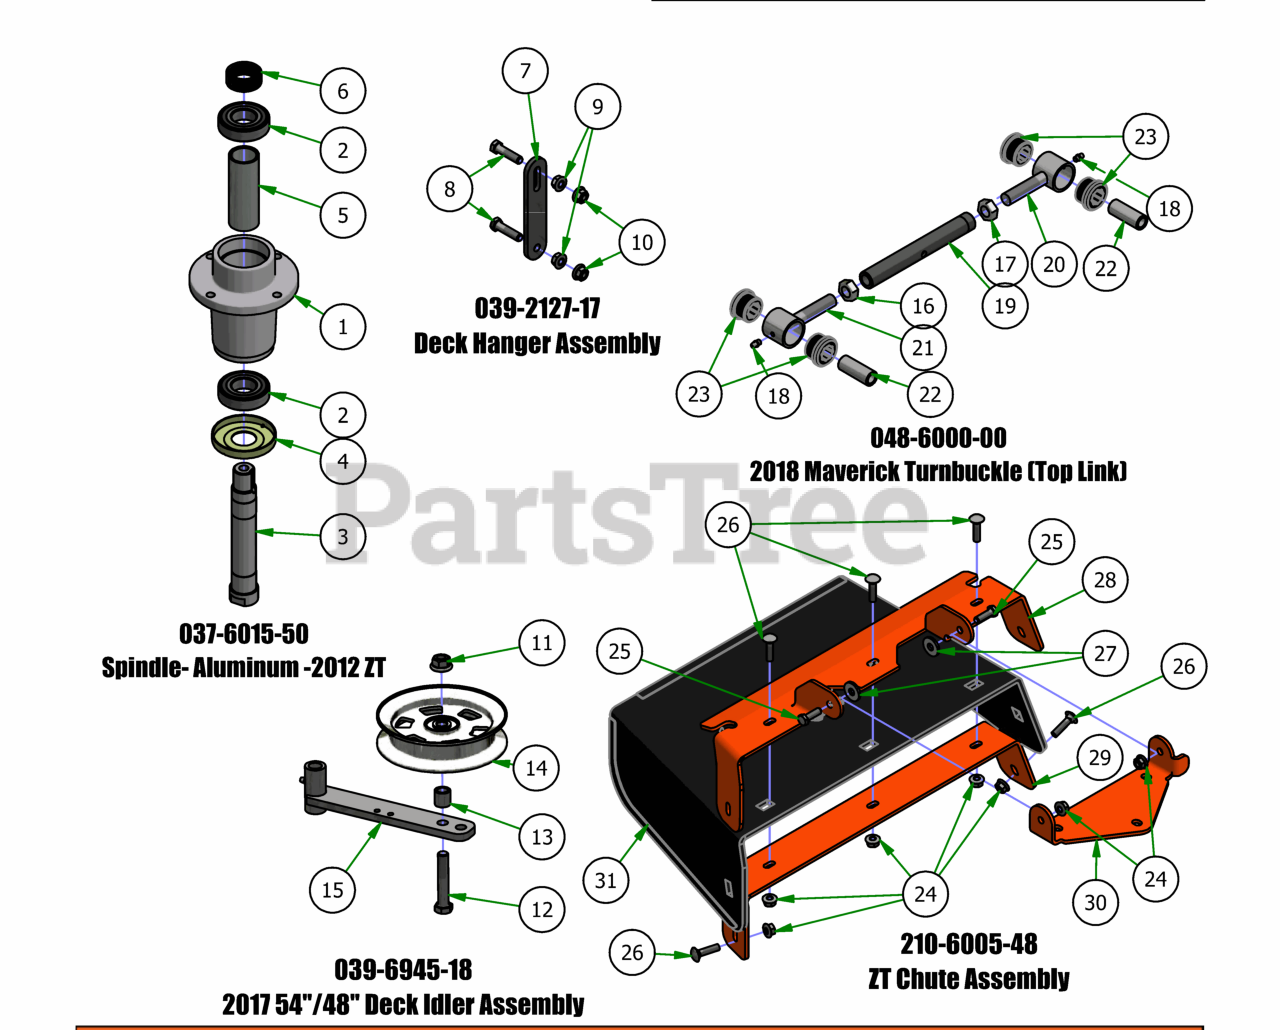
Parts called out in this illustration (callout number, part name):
1	Aluminum Spindle Housing -2010
2	Spindle Bearing, 2004 and up
3	Short Spindle Shaft w/Locking
4	Dust Cover
5	Tube Spacer for Spindle Shaft
6	Collar Spacer - Top of Spindle
7	2017 MZ/ZT Deck Hanger
8	3/8-16 X 1-1/2 HEX CAP SCREW (GR.5) ZINC
9	3/8-16 HEX SERRATED FLANGE NUT HARD/ZINC
10	3/8-16 NYLON INSERT FLANGE LOCKNUT (GR.F) ZINC
11	1/2-13 NYLON INSERT FLANGE LOCKNUT ZINC
12	1/2-13 X 2-3/4 HEX CAP SCREW (GR.5) ZINC
13	.51 ID X .75 OD X .75 LGTH SOLID SPACER ZINC
14	5" Idler Pully
15	Deck Idler
16	NUT, 5/8-18
17	NUT, 5/8-18LH
18	1/4-28 Grease Fitting
19	2018 Maverick Toplink Body
20	2018 Maverick Bushing Retainer Left-Handed
21	2018 Maverick Bushing Retainer Right-Handed
22	2018 Maverick Bushing Sleeve
23	2018 Maverick Bushing
24	5/16-18 NYLON INSERT FLANGE LOCKNUT ZINC
25	5/16-18 X 1 HEX CAP SCREW (GR.5) ZINC
26	5/16-18 X 1-1/4 CARRIAGE BOLT ZINC
27	.360 ID X .983 OD X .120 THICK FLAT WASHER NYLON
28	Discharge Upper Chute Bracket
29	Discharge Lower Chute Bracket
30	Discharge Chute Hanger (deck mounted)
31	Rubber Discharge Chute
